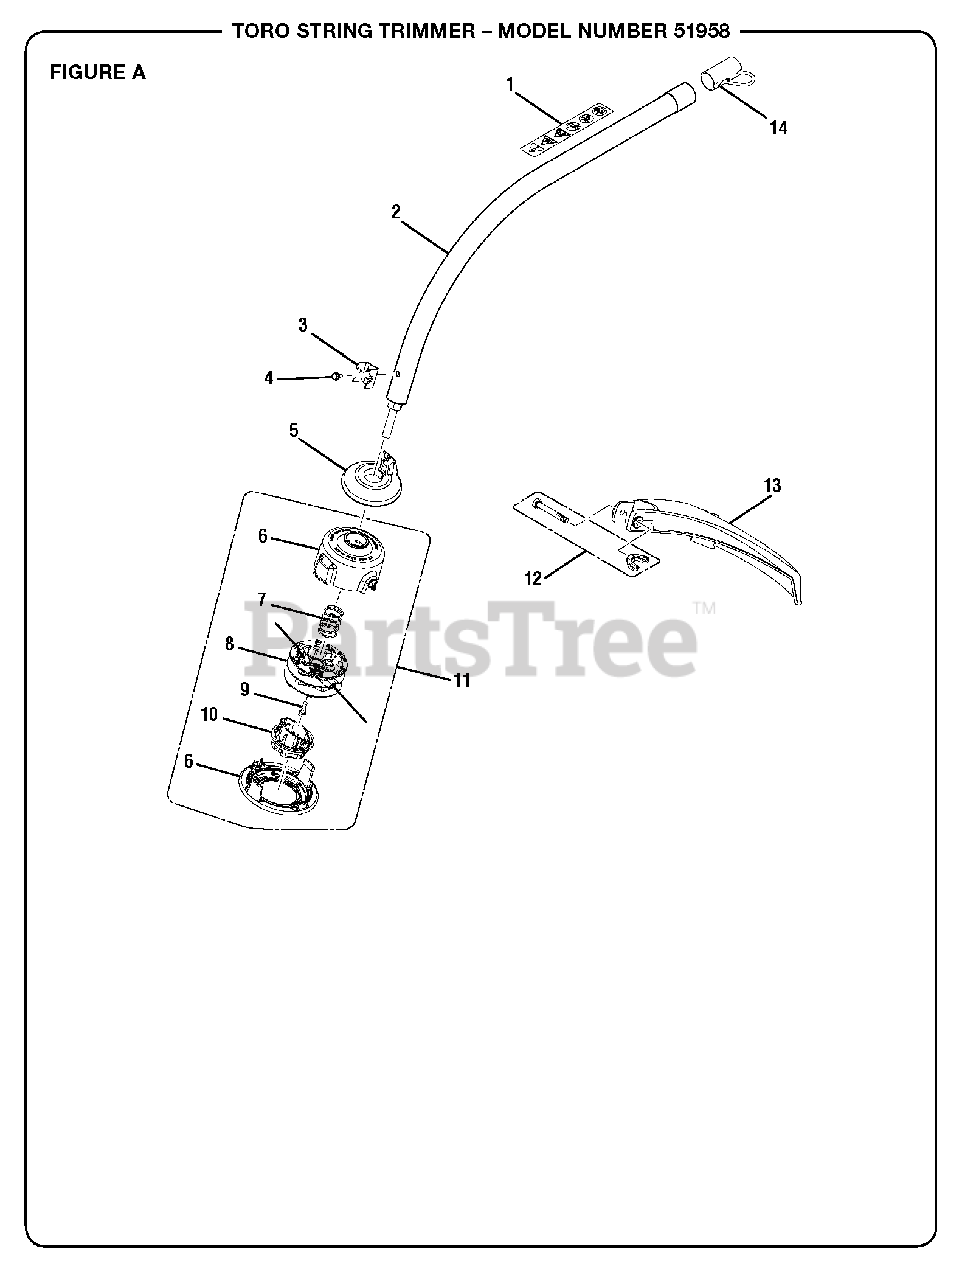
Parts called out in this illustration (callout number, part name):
1	Warning Label
2	Curved Shaft Assembly
4	Screw (#10-32 x 3/8 in., Hex Washer Hd.)
5	Grass Shield
6	Stringhead Housing
7	Compression Spring
8	Spool
9	Bolt (5/16-18 x 1/2 in.)
10	Bump Knob
11	Trimmer Head Assembly (.095)
12	Fastener Parts Kit
13	Guard
14	Hanger Cap
